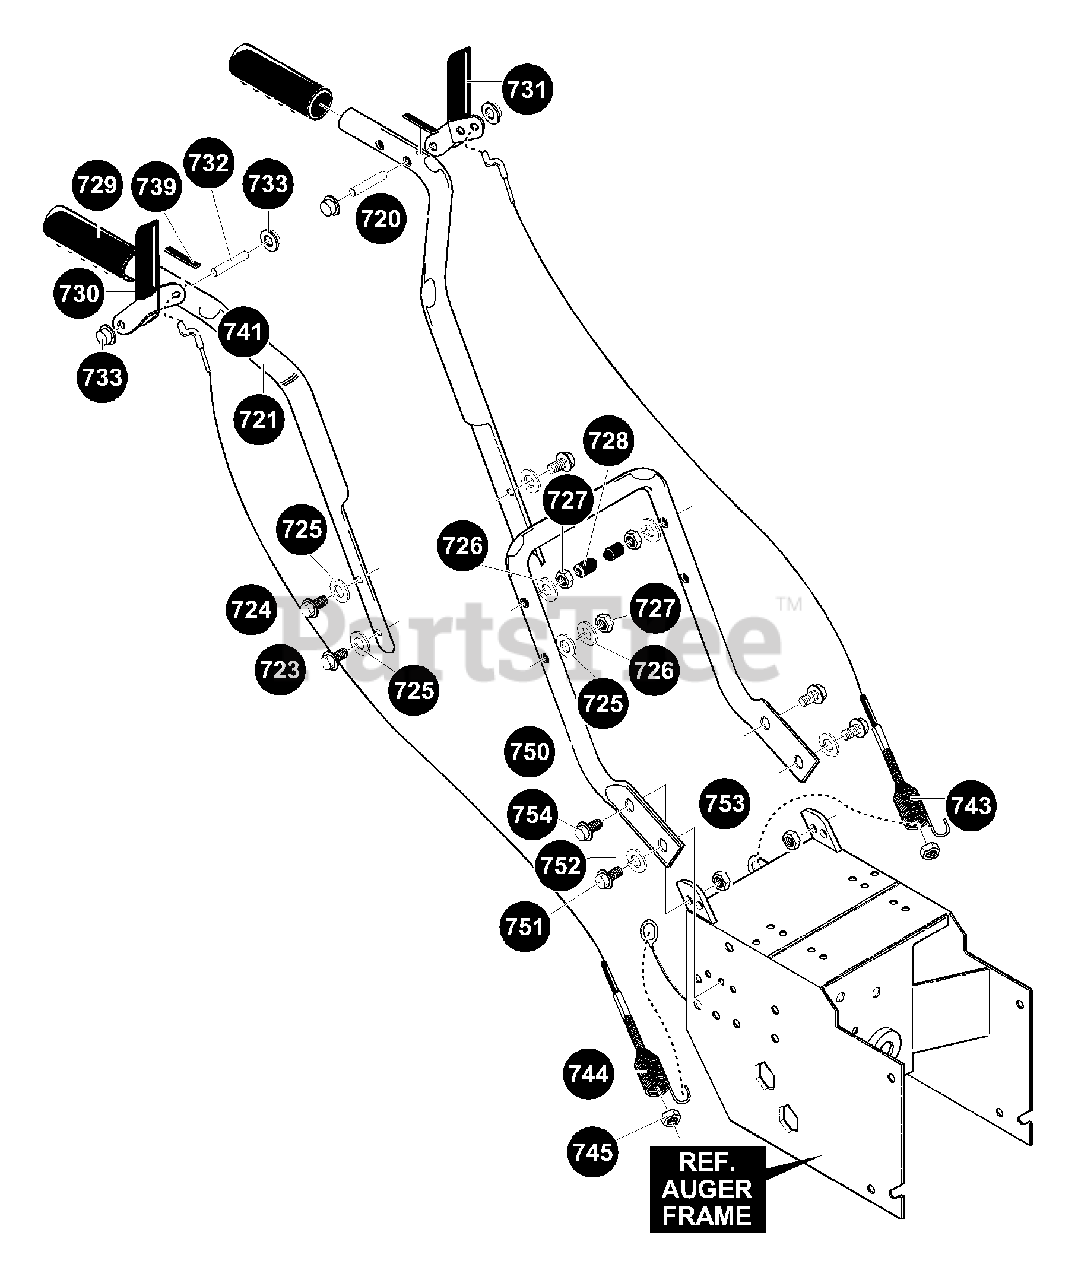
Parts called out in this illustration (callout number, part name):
720	HANDLE, UPPER LH
721	HANDLE, UPPER RH
723	SCREW, 3/8-16X2.00
724	SCREW, 3/8-16X3.00
725	WASHER, FLAT .406X .81X.065
726	WASHER, .393X.68X.10
727	NUT, 3/8-16
728	STOP, PLASTIC
729	GRIP, HANDLE
730	HANDLE-CLUTCH
731	HANDLE, ASSY CL LH
732	PIN, PIVOT
733	NUT, PUSH ON CAP
739	BUMPER, RECT
741	CABLE, CLUTCH
743	SPRING, TENSION
744	SPRING, AUGER CLUTCH
745	NUT, 1/4-20 RGHXCTRLK
750	HANDLE, LOWER
751	SCREW, 5/16-18X .50
753	NUT, 5/16-18
754	SCREW, 5/16-18X .75
